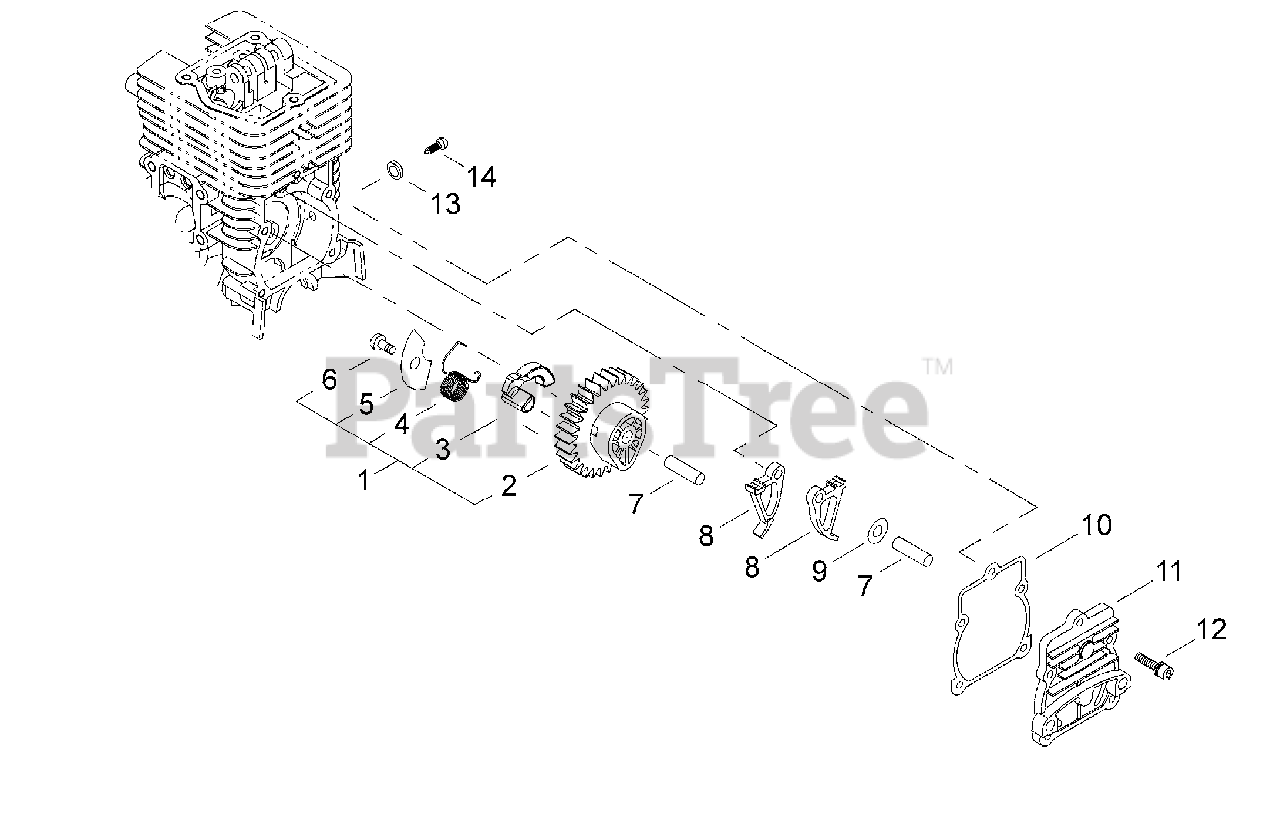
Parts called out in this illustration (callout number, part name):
1	CAM GEAR ASSY
2	GEAR, CAM
3	WEIGHT
4	SPRING
5	PLATE, COVER
6	SCREW, TAPPING 4×6
7	PIN, LOCATING Ø5×29.8 MM
8	FOLLOWER, CAM
9	WASHER 5 MM
10	GASKET, CAM GEAR
11	COVER, CAM GEAR
12	BOLT M4×14
13	WASHER Ø10ר5.5×2
14	SCREW M5
